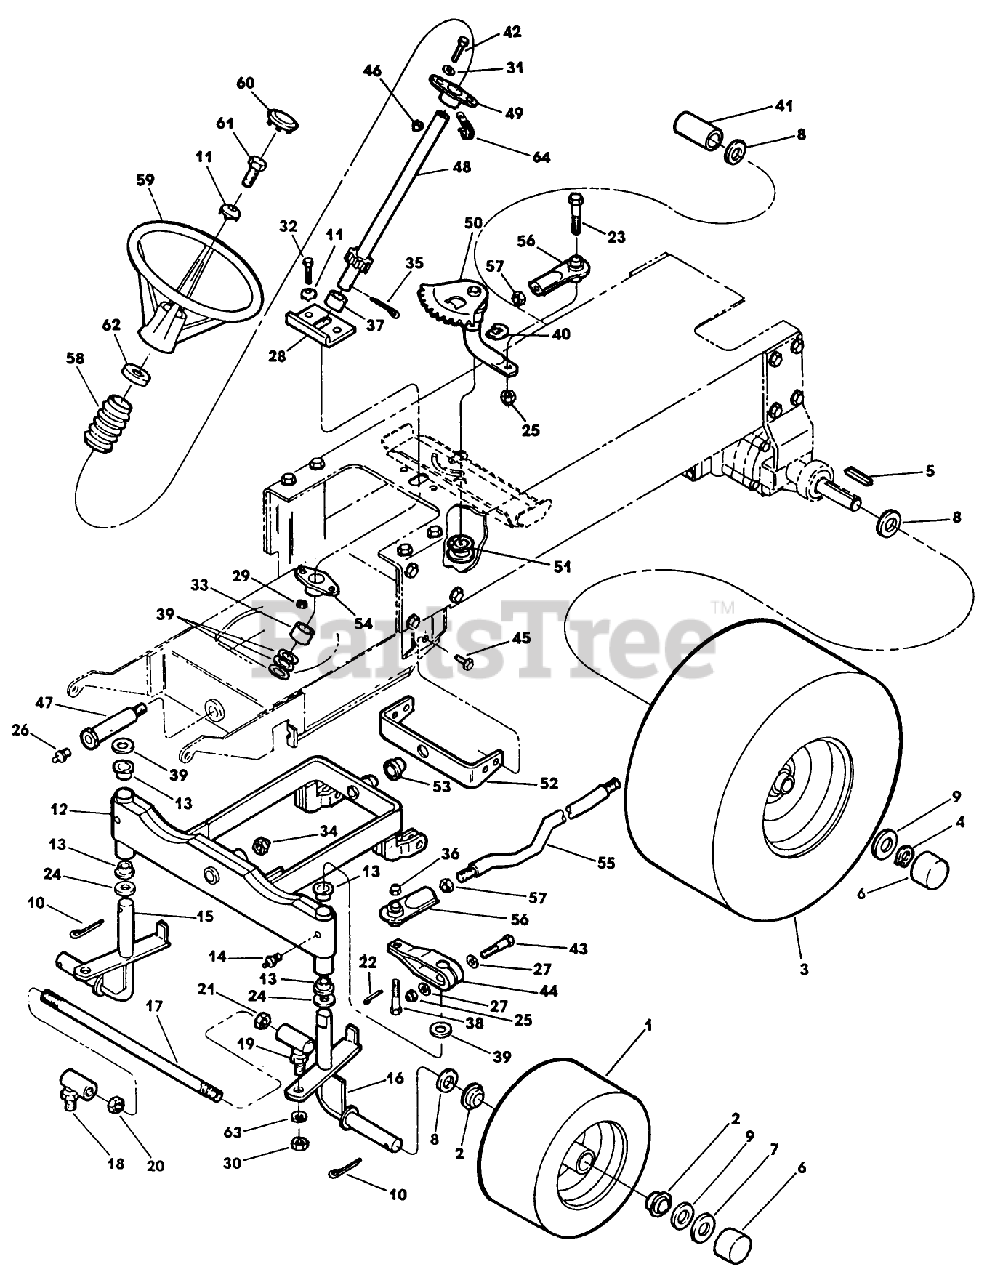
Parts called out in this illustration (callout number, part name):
12	AXLE AY-FRONT
13	BEARING - BRONZE
16	SPINDLE ASM - LH
18	BALL JOINT, RH
19	BALL JOINT-LH
21	NUT HEX JAMB LH
24	WASHER - THRUST
25	NUT-LOCKING
30	HEX NUT
34	NUT-HEX
41	SPACER-WHEEL
42	SCREW-HH
46	NUT-LOCK, CONE
49	BEARING AY.
56	BALL JOINT
57	NUT-HEX
60	CAP
61	SCREW - HEX
64	CLAMP - J EX
